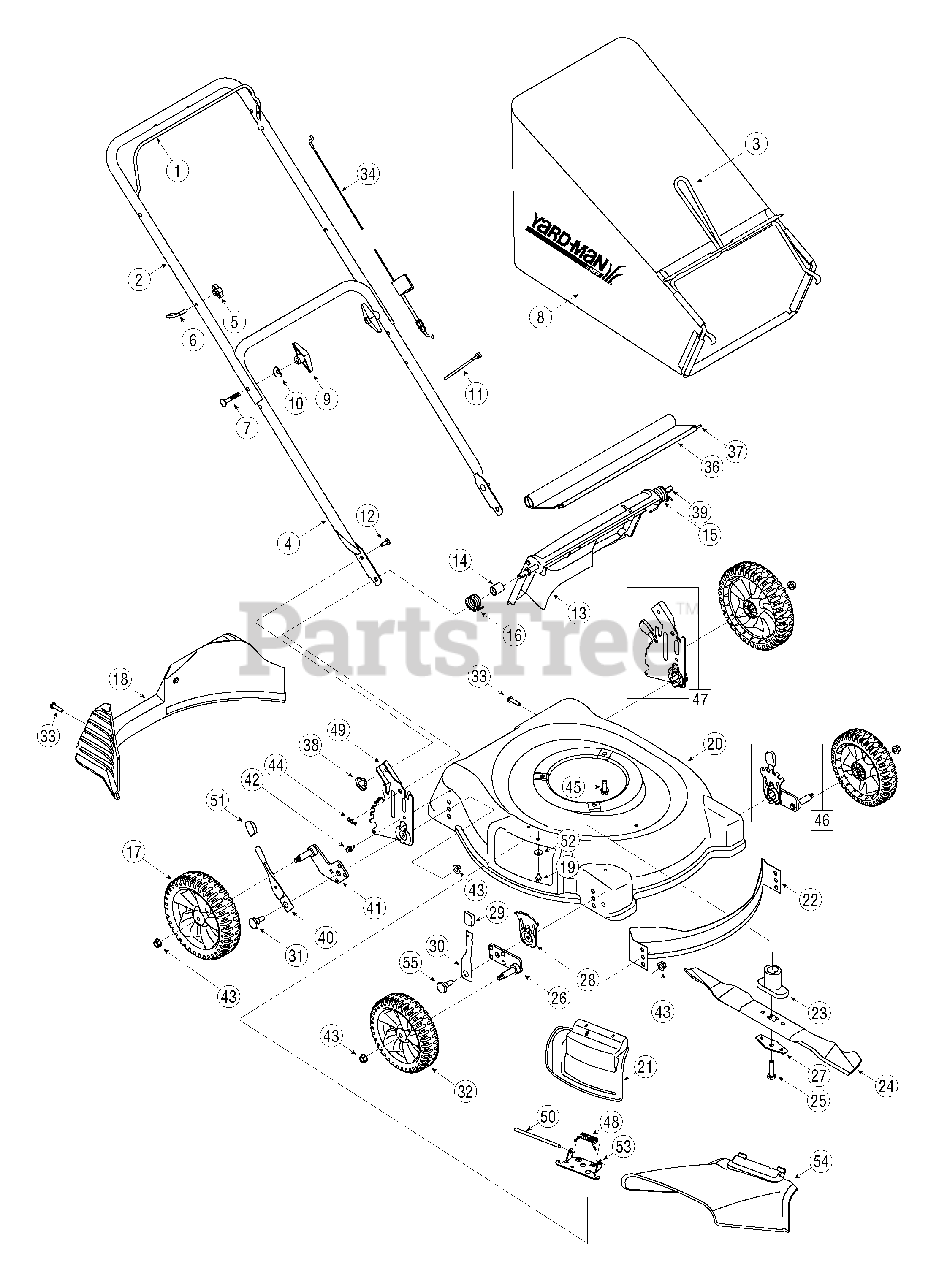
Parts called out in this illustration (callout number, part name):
5	Wing Nut
6	Rope Guide
7	Carriage Bolt,5/16-18 x 2
8	Grass Bag Assembly
9	Hand Knob
10	Saddle Washer
11	Cable Tie
12	Carriage Bolt,1/4-20
13	Rear Discharge Door
14	Spacer
15	Torsion Spring - LH
16	Torsion Spring - RH
17	Rear Wheel, 8 x 1.8
18	Rear Baffle
19	Screw, 1/4-20 x .500
22	Front Baffle
23	Blade Adapter
24	Mulching Blade
25	Hex Screw, 3/8-24 x 2.5
26	Pivot Arm Assembly - RH
26	Pivot Arm Assembly - LH Not Pictured
27	Blade Bell Support
28	Front Adjustment Plate
29	Adjustment Lever Knob
30	Spring Lever Assembly
31	Shoulder Screw
32	Front Wheel, 7 x 1.8
33	Screw, 1/4-15 x 1.250
34	Control Cable - 53" Snap
35	Flange Lock Nut, 1/4-20
36	Trailshield
37	Trailshield Wire
38	Wing Nut, 1/4-20
39	Rear Door Pivot Rod
40	Spring Lever
41	Pivot Arm Assembly - RH
41	Pivot Arm Assembly - LH Not Pictured
42	AB Screw
43	Flange Lock Nut, 3/8-16
44	Hairpin Clip
45	TT Sems Screw, 3/8-16 x 1.0
46	Ht. Adj. Assy. Front - LH
46	Ht. Adj. Assy. Front - RH Not Pictured
47	Rear Handle Bracket Assy. - LH
47	Rear Handle Bracket Assy. - RH Not Pictured
48	Torsion Spring
49	Handle Bracket Assembly use ref # 47
50	Hinge Pin
51	Spring Lever Grip
52	Bell Washer
53	Deflector Chute Adaptor
54	Side Chute
55	Shoulder Screw
